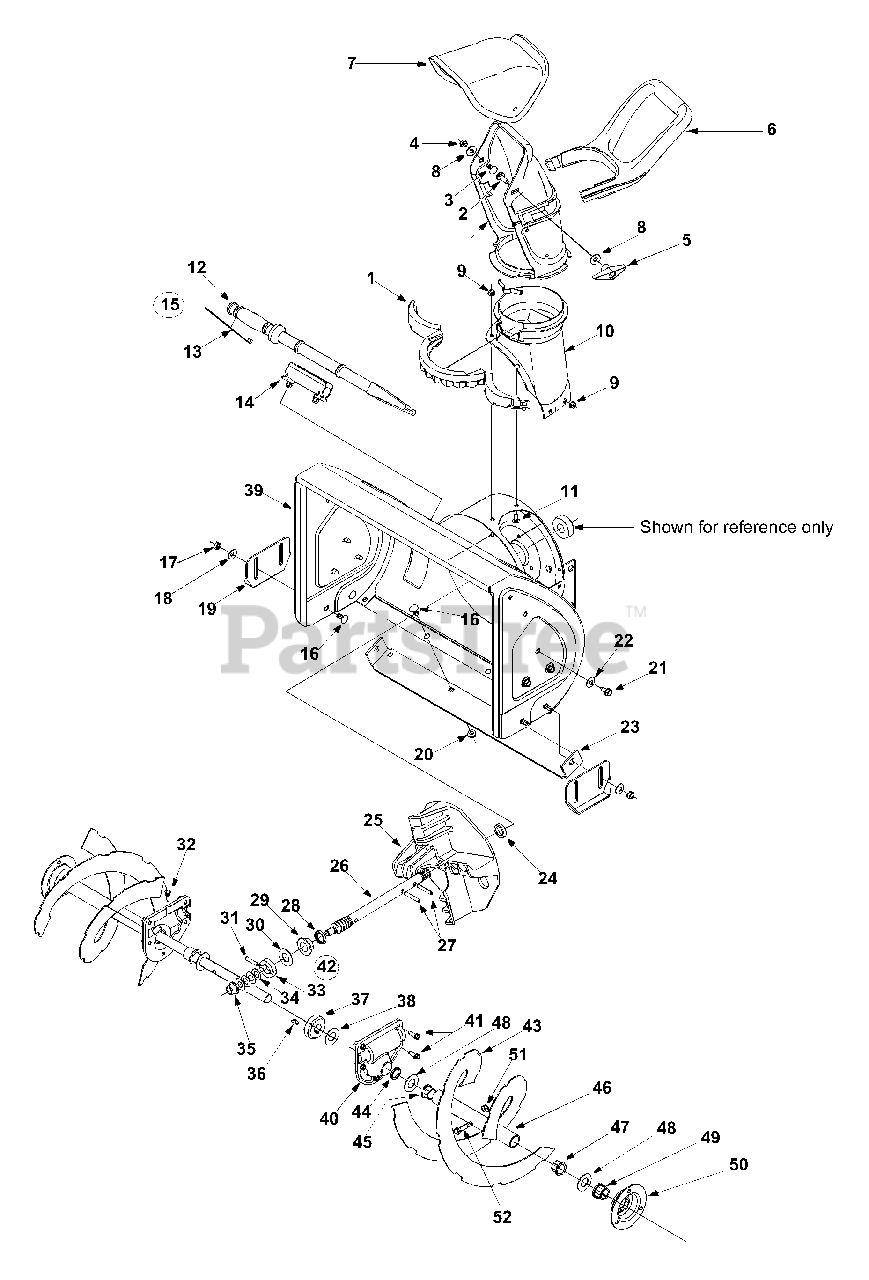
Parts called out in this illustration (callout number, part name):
1	Chute Assembly
2	Carriage Bolt 5/16-18 x 1.0"
3	Carriage Bolt 5/16-18 x 0.750"
4	Patch Nut
5	Chute Knob Assembly
6	Chute Handle
7	Upper Chute
8	Washer
9	Lock Nut 1/4-20
10	Lower Chute
11	Carriage Screw 1/4-20 x 0.62"
12	Chute Clean-out Tool
13	Cable Tie
14	Mounting Bracket: Chute Tool
15	Chute Clean-Out Tool Assy. Comp.
16	Carriage Bolt 5/16-18 x 0.75"
17	Hex Nut 5/16-18
18	Beleville Washer
20	Flange Lock Nut
21	AB Screw 5/16-12
22	Bell Washer
24	Spacer
25	Impeller
26	Worm Shaft
27	Spiral Pin
28	Oil Seal
29	Flange Bearing
30	Flat Washer
31	Spiral Pin
33	Thrust Collar
34	Flat Washer
35	Flange Bearing
36	Key
37	Worm Gear 20T
38	Flat Washer
40	Reducer Housing Assembly LH
41	TT Screw 1/4-20 x 0.75"
42	Gearbox Assembly: Auger
43	Spiral Assembly
44	Oil Seal
45	Flange Bushing
46	22" Auger Shaft
47	Flange Bushing
48	Flat Washer
49	Hex Flange Bearing
51	Hex Lock Nut 5/16-18
52	Shear Bolt 5/16-18 x 1.5"
